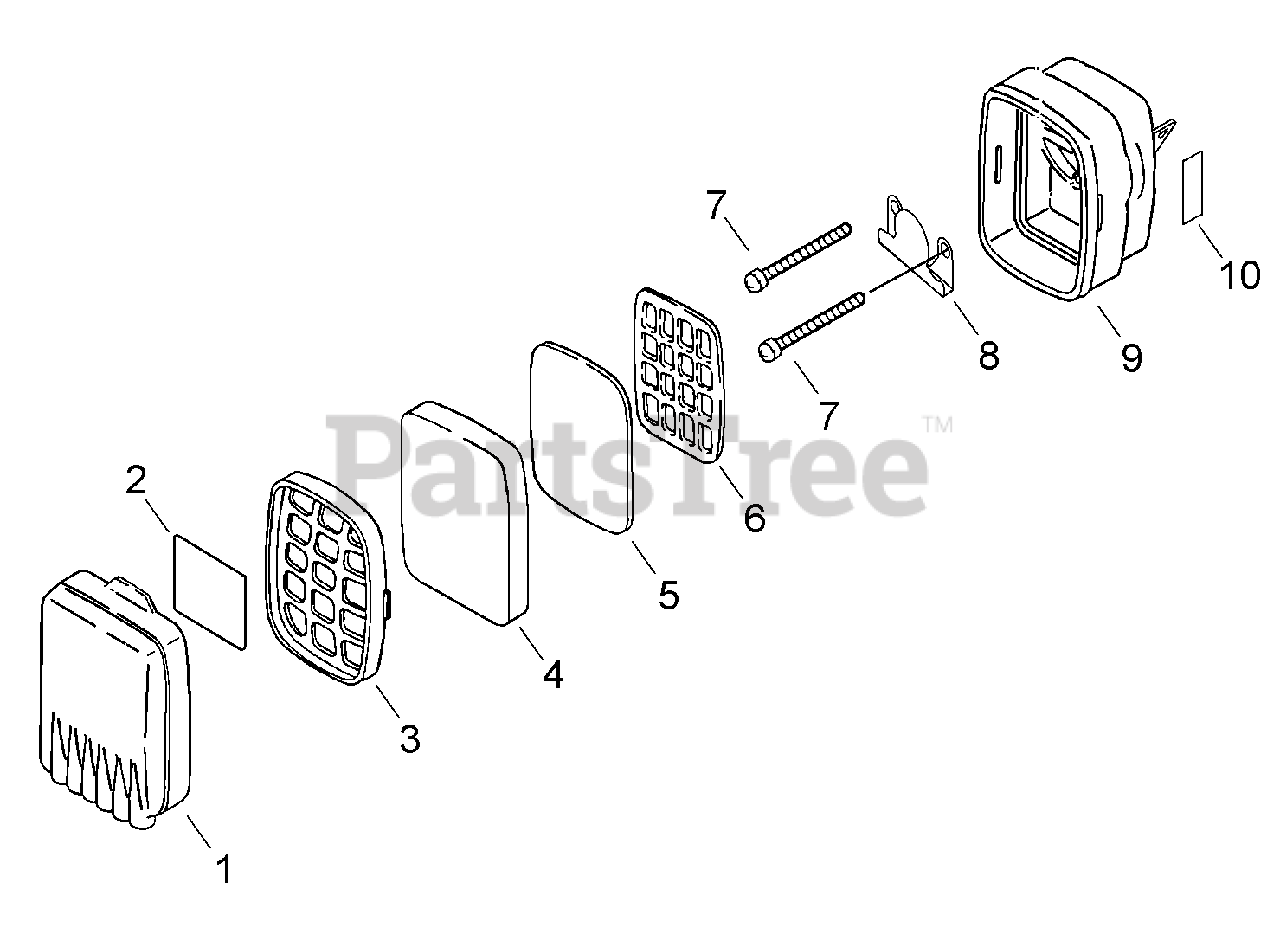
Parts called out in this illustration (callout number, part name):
1	COVER, AIR FILTER
2	LABEL - AIR FILTER
3	RETAINER, AIR FILTER
4	PRE-FILTER -- FOAM
5	FILTER, AIR
6	RETAINER, AIR FILTER
7	SCREW - 5X60
8	PLATE, PREVENT
9	CASE, AIR FILTER
10	LABEL - CHOKE
